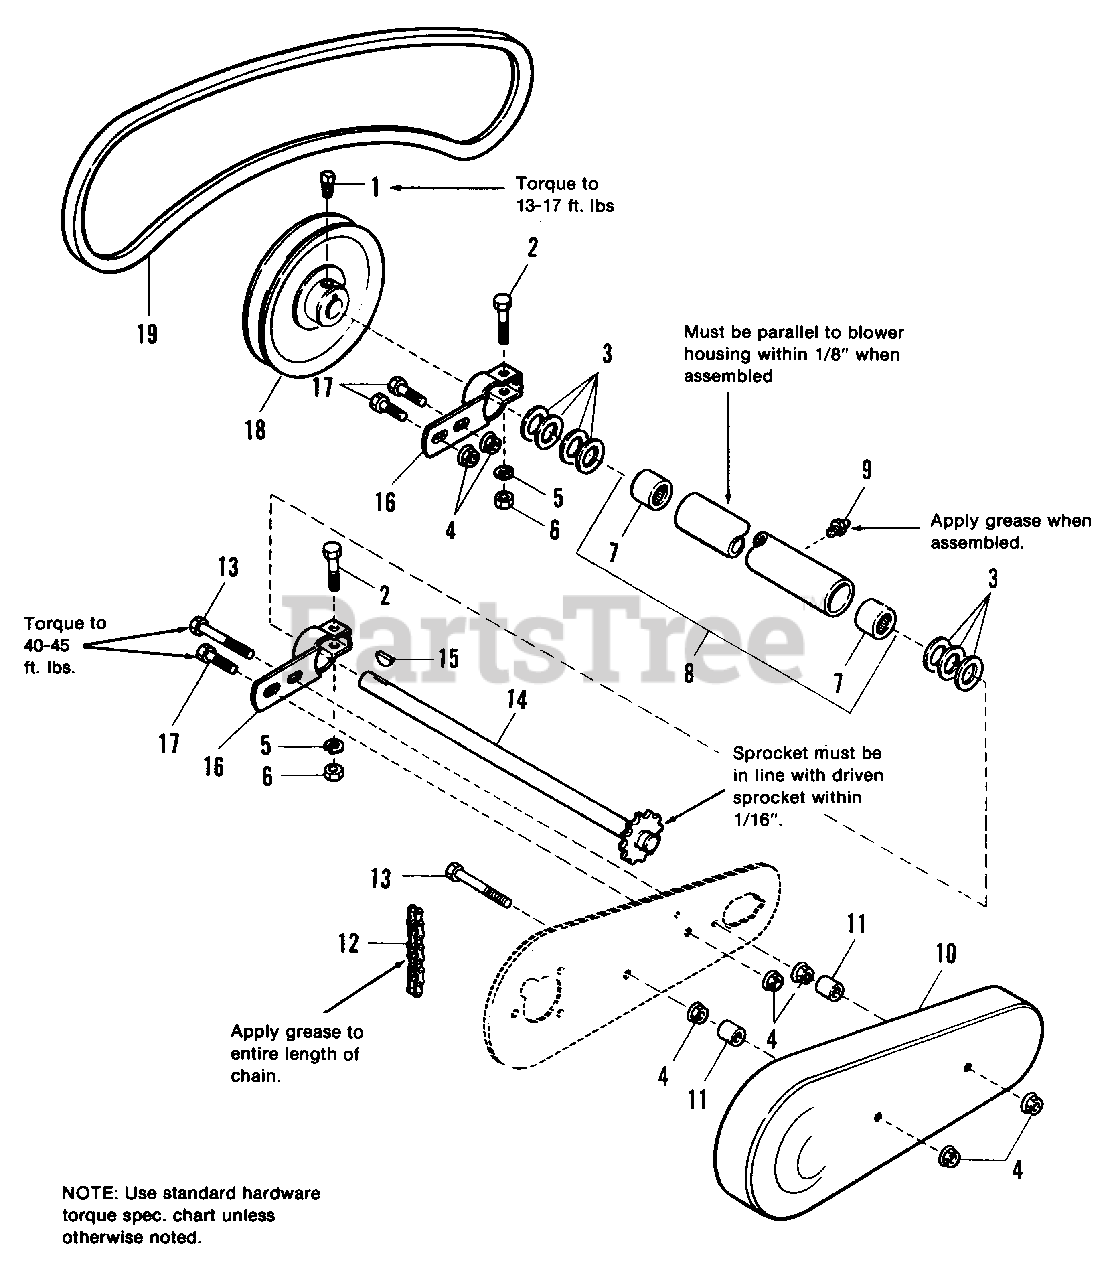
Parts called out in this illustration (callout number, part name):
1	SETSCREW, Sq. Hd., 5/16-18 x 1/2
2	CAPSCREW, Hex Hd., 5/16-18 x 1-3/4
4	LOCKNUT, Flange, 3/8-16
5	LOCKWASHER, 5/16
6	NUT, 5/16
7	BEARING, Needle
8	BEARING & HOUSING ASSY. (36" only)
8	BEARING & HOUSING ASSY. (42" only)
9	FITTING, Grease
10	GUARD, Chain
13	SCREW, Whizlock, 3/8-16 x 2-3/4
14	SHAFT ASSY. (36" only)
14	SHAFT ASSY. (42" only)
15	KEY, Woodruff, #9, 3/16 x 3/4
16	CLAMP, Housing
17	SCREW, Whizlock, 3/8-16 x 1
